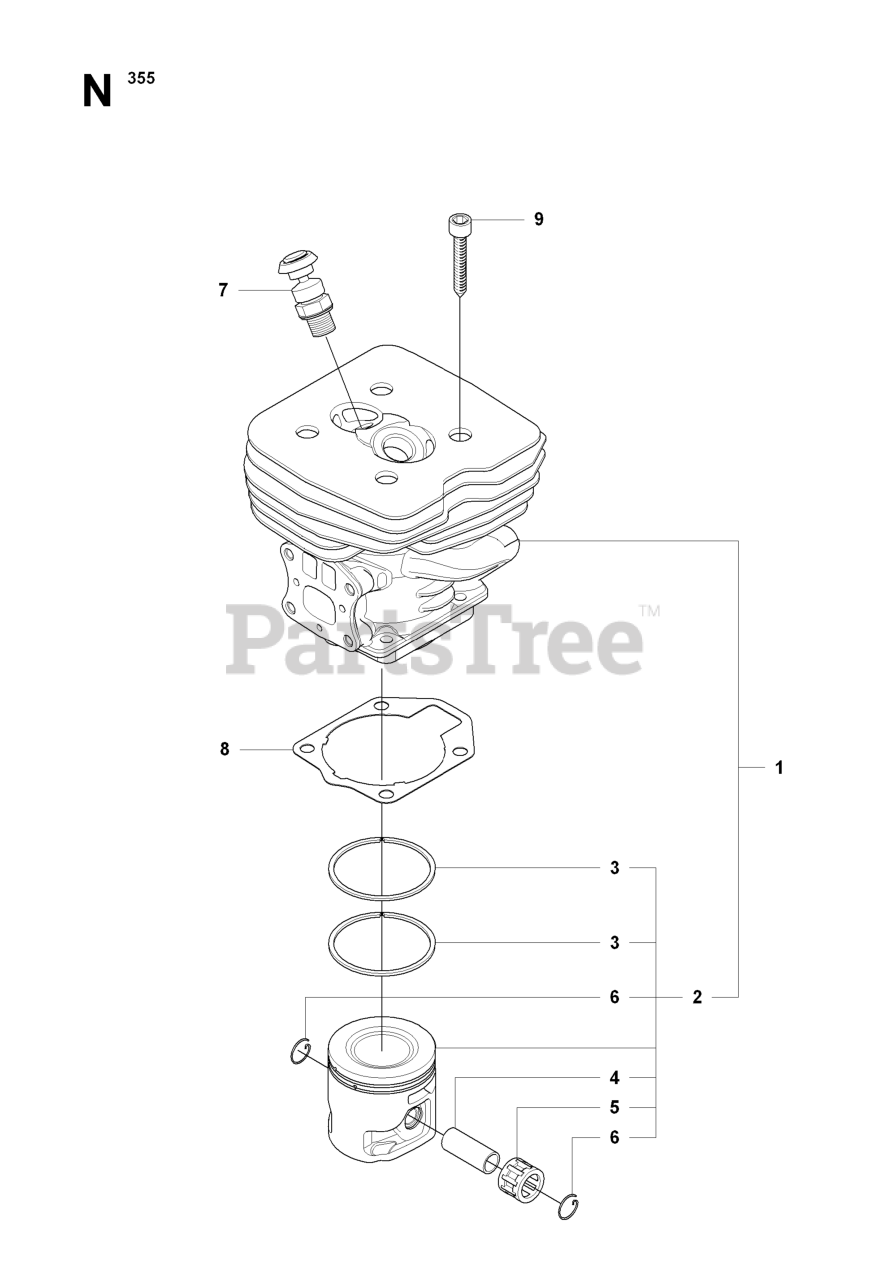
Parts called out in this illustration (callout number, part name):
1	CYLINDER ASSY
2	%PISTON ASSY
3	PISTON RING
4	PISTON PIN
5	SUPPORT BUSHING
7	DECOMPRESSION VALVE
9	SCREW MC6S 5X25
